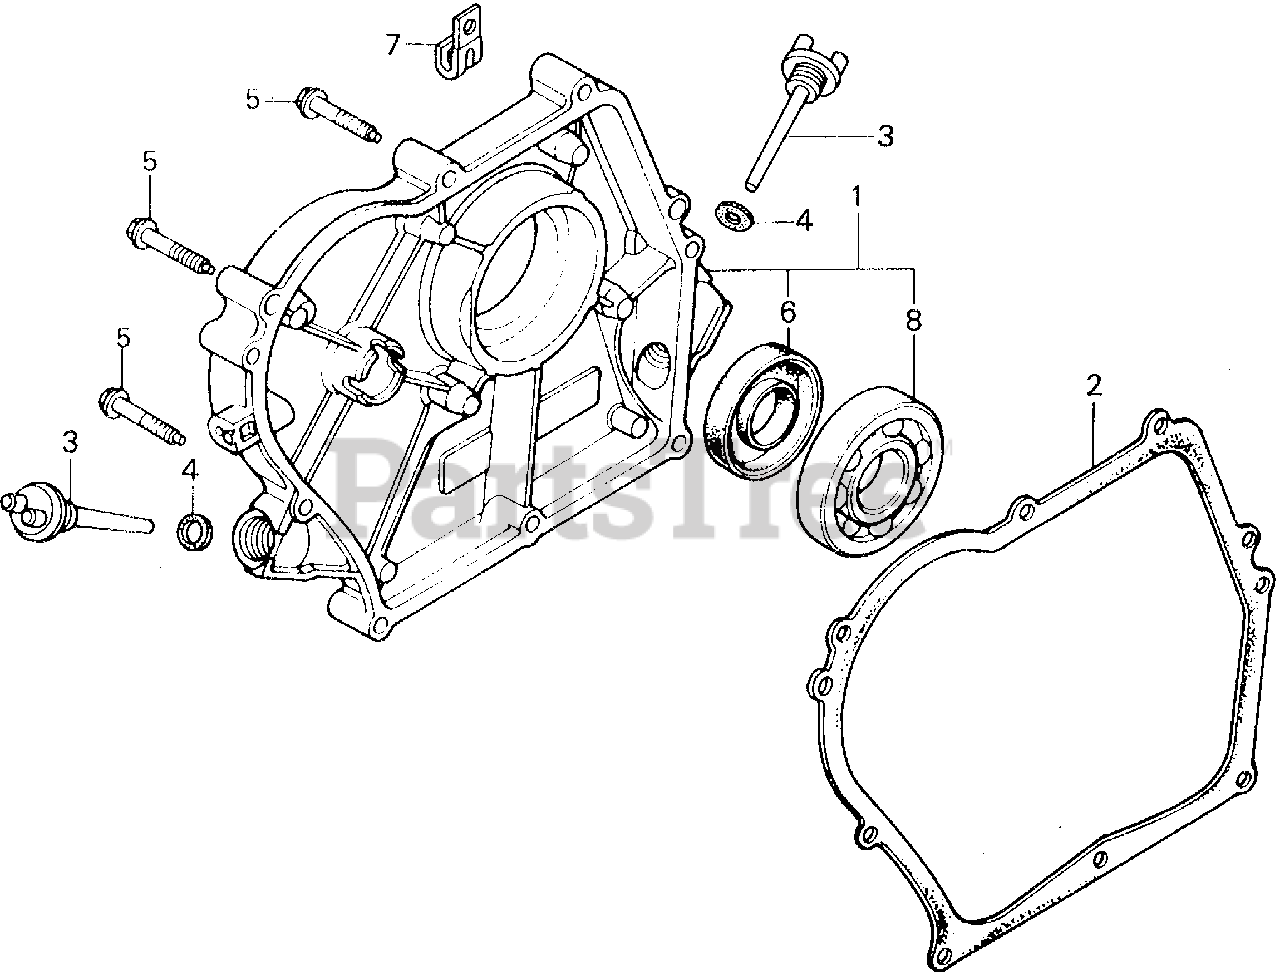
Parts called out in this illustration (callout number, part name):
1	COVER ASSY., CRANKCASE (S-TYPE)
2	GASKET, COVER
4	GASKET, OIL FILLER CAP
5	BOLT, FLANGE (6X32)
6	OIL SEAL (25X41X6)
7	CLIP, CABLE
8	BEARING, RADIAL BALL (6205)
